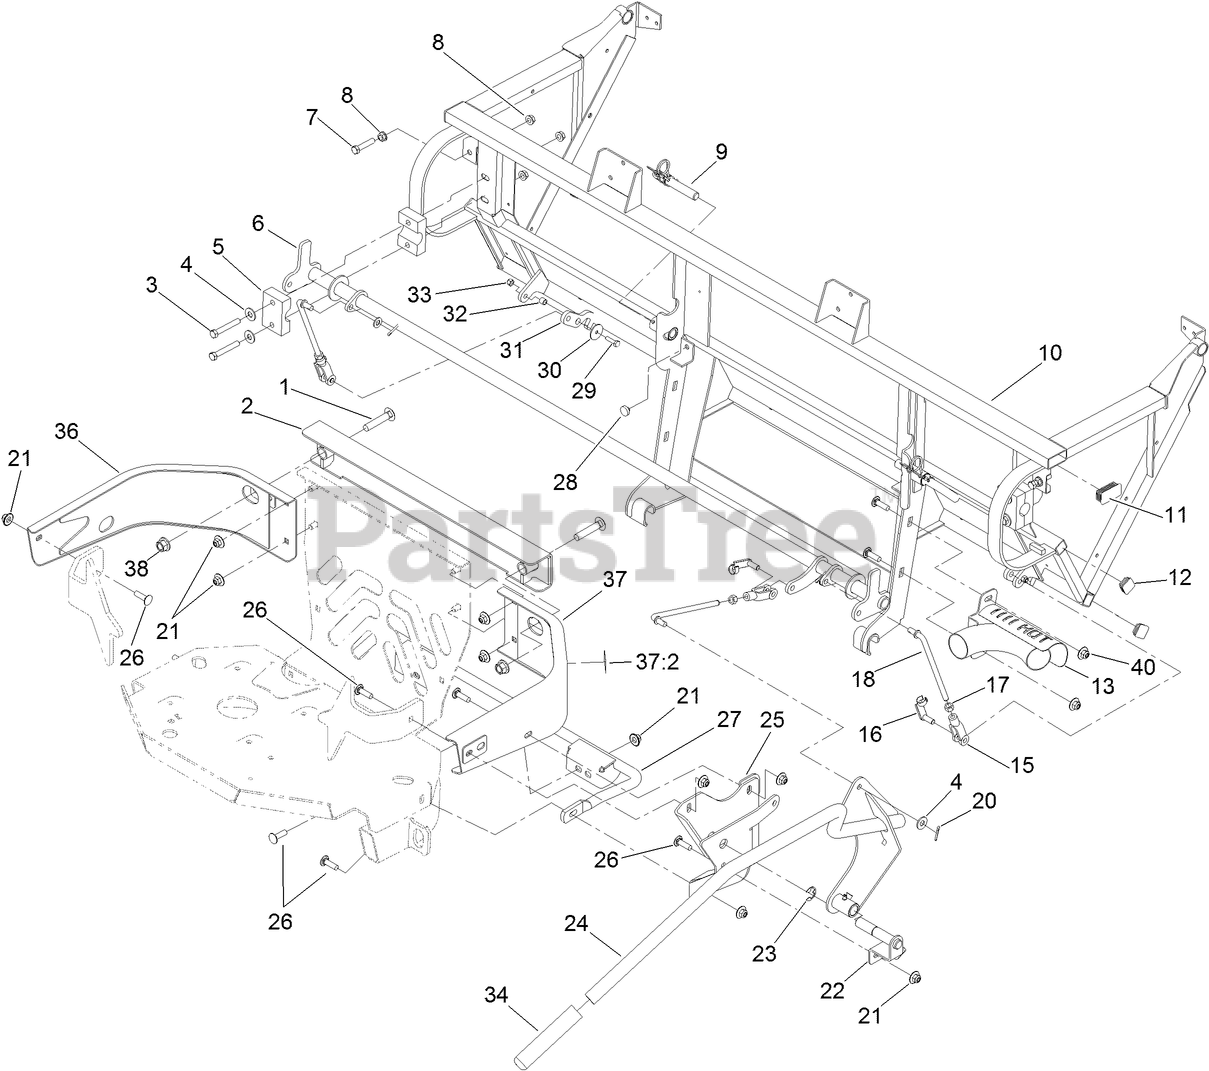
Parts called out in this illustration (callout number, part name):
1	SCREW-CARR
2	MOUNT-BAGGER, UPPER
3	SCREW-HH
4	WASHER-FLAT
5	HALF-BLOCK, BEARING
6	LINK-INTERMEDIATE
7	SCREW-HH
8	NUT-HHF, WHIZ
9	PIN-MOUNT, BAGGER
13	EXHAUST DIVERTER ASM
15	YOKE-LINKAGE, BRAKE
16	Pin-Spring, Clevis
17	NUT-HEX
18	LINK-HANDLE
20	PIN-COTTER
21	NUT-FLANGE, NI
22	PIN-HANDLE
23	E-RING
24	BAGGER HANDLE ASM
25	MOUNT-PIVOT
26	SCREW-CARR
27	MOUNT-BAGGER, LOWER
28	BUMPER
29	SCREW-HH
30	WASHER-FLAT
32	SPACER
33	NUT-LOCK, NI
34	HANDLE-GRIP
36	BUMPER-RH
37	LH BUMPER ASM
37:2	DECAL-CAUTION
38	NUT-LOCK
40	NUT-HF, NI
